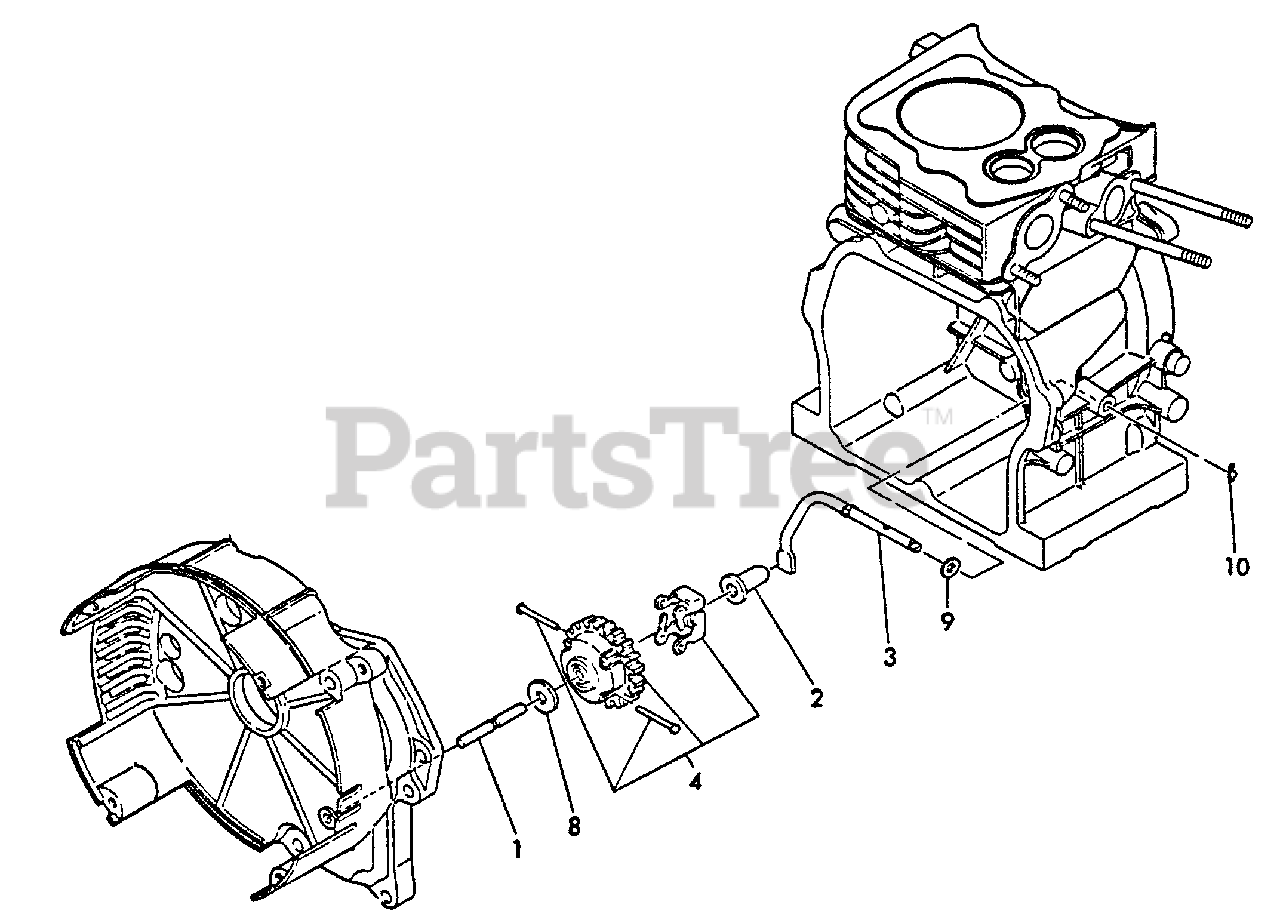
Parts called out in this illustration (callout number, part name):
1	SHAFT, GOVERNOR
2	SPINDLE, GOVERNOR
3	YOKE, GOVERNOR
4	GOVERNOR GEAR ASSY
8	WASHER
9	WASHER - 6
10	PIN - 6 -- SNAP
